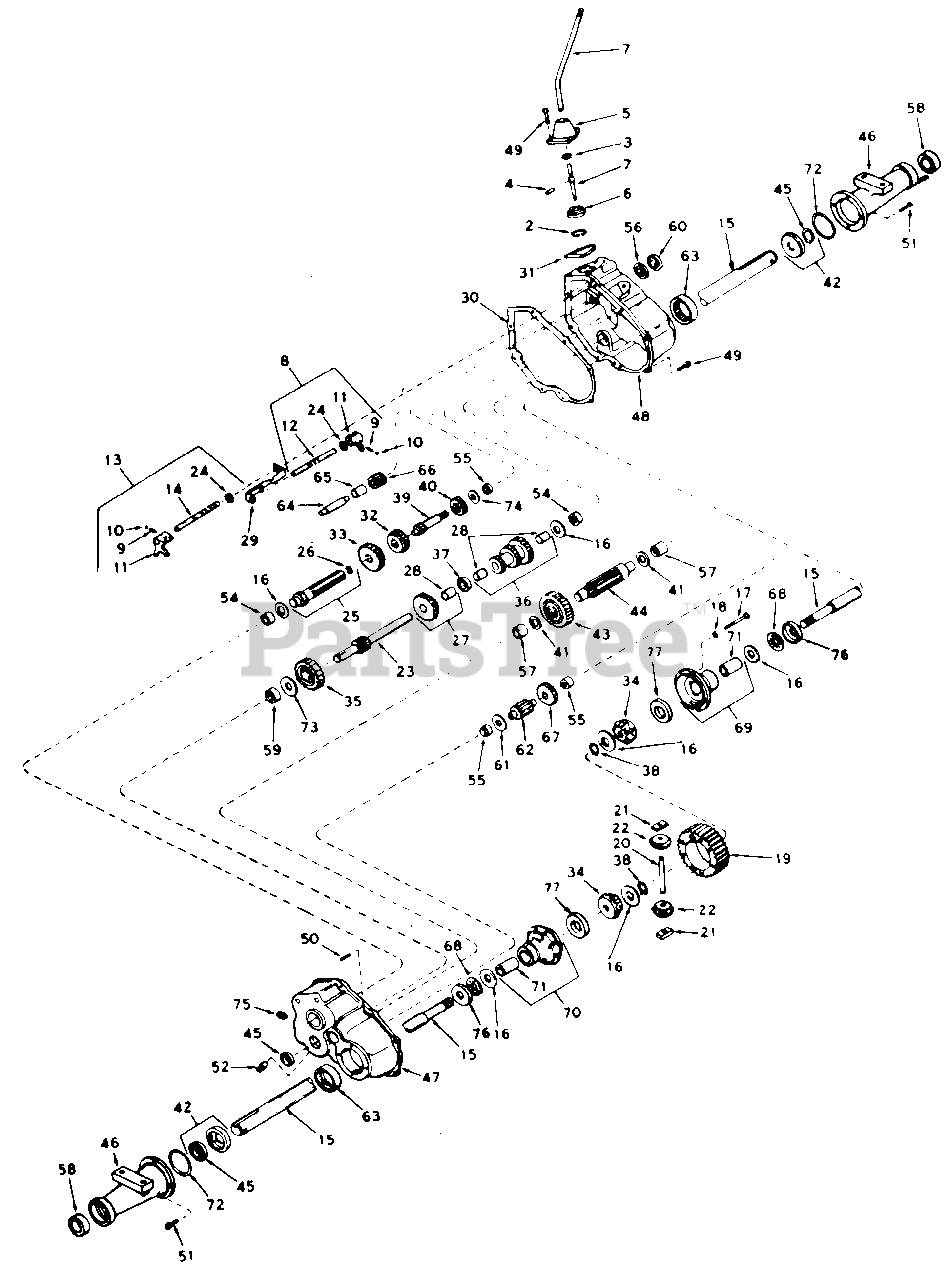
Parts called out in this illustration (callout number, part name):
2	Ring, Snap
3	Ring, Quad
4	Pin, Roll
5	Housing, Shift Lever
6	Keeper, Shift Lever
7	Lever, Shift
8	Rod Ass'y. Shift
9	Spring
10	Ball, Steel
11	Fork. Shifter
12	Rod, Shifter
13	Rod Ass'y., Shift
14	Rod, Shifter
15	Axle (18-11/32" Long)
16	Washer, Thrust
17	Scr., Hex Hd., 1/4-20 x 2-1/2
18	Lock Washer, 1/4"
19	Gear, Ring
20	Pin, Drive
21	Block, Drive
22	Pinion, Bevel
23	Shaft and Gear, Brake
24	Ring, Snap
25	Shaft and Bearing Ass'y., Pinion
26	Bearing, Needle
27	Gear Cluster Ass'y.
28	Bushing
29	Stop, Shifter
30	Gasket, Case and Cover
31	Gasket, Shifter Lever Housing
32	Gear, Shifting
33	Gear, Shifting
34	Gear, Bevel
35	Gear, Idler
36	Gear Cluster Ass'y.
37	Spacer
38	Ring, Snap
39	Shaft, Input
40	Spur Gear, Input Shaft
41	Washer, Thrust
42	Seal and Retainer Ass'y., Oil
43	Gear, Output
44	Pinion, Output
45	Seal, Oil
46	Housing, Axle
47	Cover Ass'y., Transaxle
48	Case Ass'y., Transaxle
49	Screw, Socket Hd., 1/4-20 x 3/4
50	Pin, Dowel
51	Screw, Hex Hd. Sems, 5/16-18 x 1
52	Plug, Magnetic Drain
54	Bearing, Needle
55	Bearing, Needle
56	Bearing, Ball
57	Bearing, Needle
58	Bearing, Ball
59	Bearing, Needle
60	Seal, Oil
61	Washer
62	Shaft and Pinion
63	Bearing, Needle
64	Shaft, Reverse Idler
65	Spacer, Reverse Idler
66	Idler, Reverse
67	Spur Gear (22 Teeth)
68	Bearing, Thrust
69	Carrier Ass'y., Differential
70	Carrier Ass'y, Differential
71	Bushing
72	O Ring
73	Washer, Thrust
74	Washer, Thrust
75	Plug, Pipe
76	Race, Thrust
77	Washer
